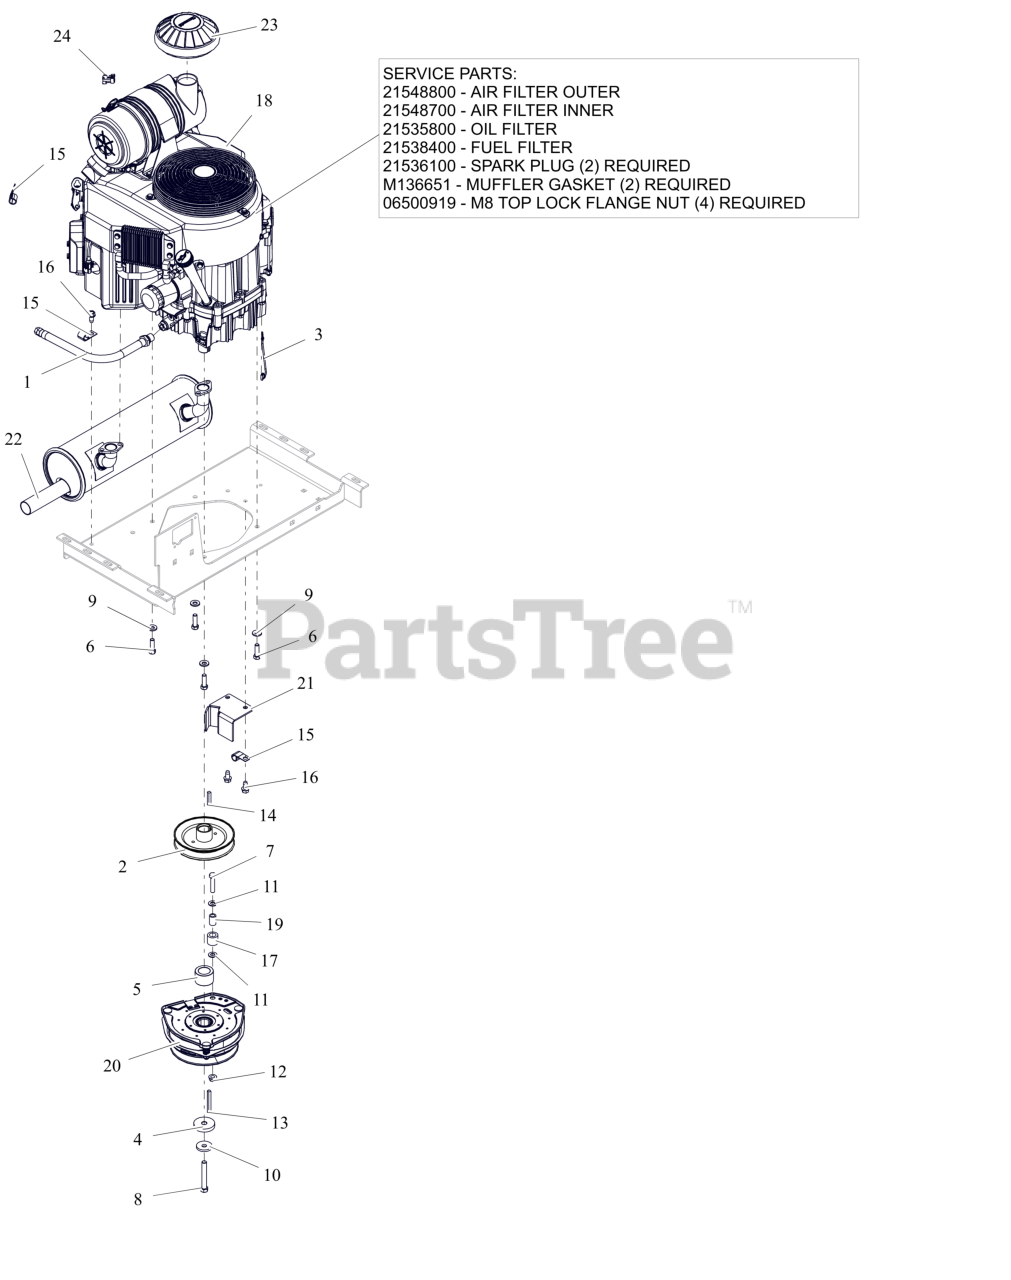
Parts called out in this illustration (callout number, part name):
1	HOSE, OIL DRAIN
2	WLDMT, TRANSAXLE DRIVE PULLEY
3	LEAD - STARTER SOLENOID
4	SPACER, .474/.459X2.00X.350
5	SPCR, 1.125 x 1.750 x 1.147
6	BLT, HEX .38-16X1.25 G5 ZCC NT
7	BLT, HEX .38-16X1.75 G5 ZCC
8	BLT, HEX 0.4375-20X3 G8 ZCC NT
9	WASHER, 3/8" SPRING DISC
10	WASHER, 7/16" SPRING DISK
11	WSHR,FLT .406X.812X.065 ZCC
12	NUT-LK-CTR-FLG .375-16 GF ZCC
13	KEY-SQ .25 X 2.50 X .25 SAE
14	KEY-SQ .25 X 1.50 X .25 SAE
16	SCR,TAP .375-16X.75 HWH TR ZCC
17	BUMPER,RUBBER .62X1.0X.88 LG
18	ENGINE, KAWASAKI FX850
18	FILTER, OUTER
18	FILTER, INNER - KAW
18	FILTER,OIL - KAW
18	FUEL FILTER - KAWASAKI
18	PLUG, SPARK
18	GASKET, MUFFLER #
18	NUT-LK-TOP-FLG M8 ZCC
19	BUSH.,S.391X.622X.950 ST
20	CLUTCH, OGURA GT3.5-AR04
21	WLDMT, CLUTCH STOP (BLACK)
22	MUFFLER, KAWASAKI FX850
23	CAP, AIR CLEANER INTAKE (2")
24	CLIP, T, .38-.50
